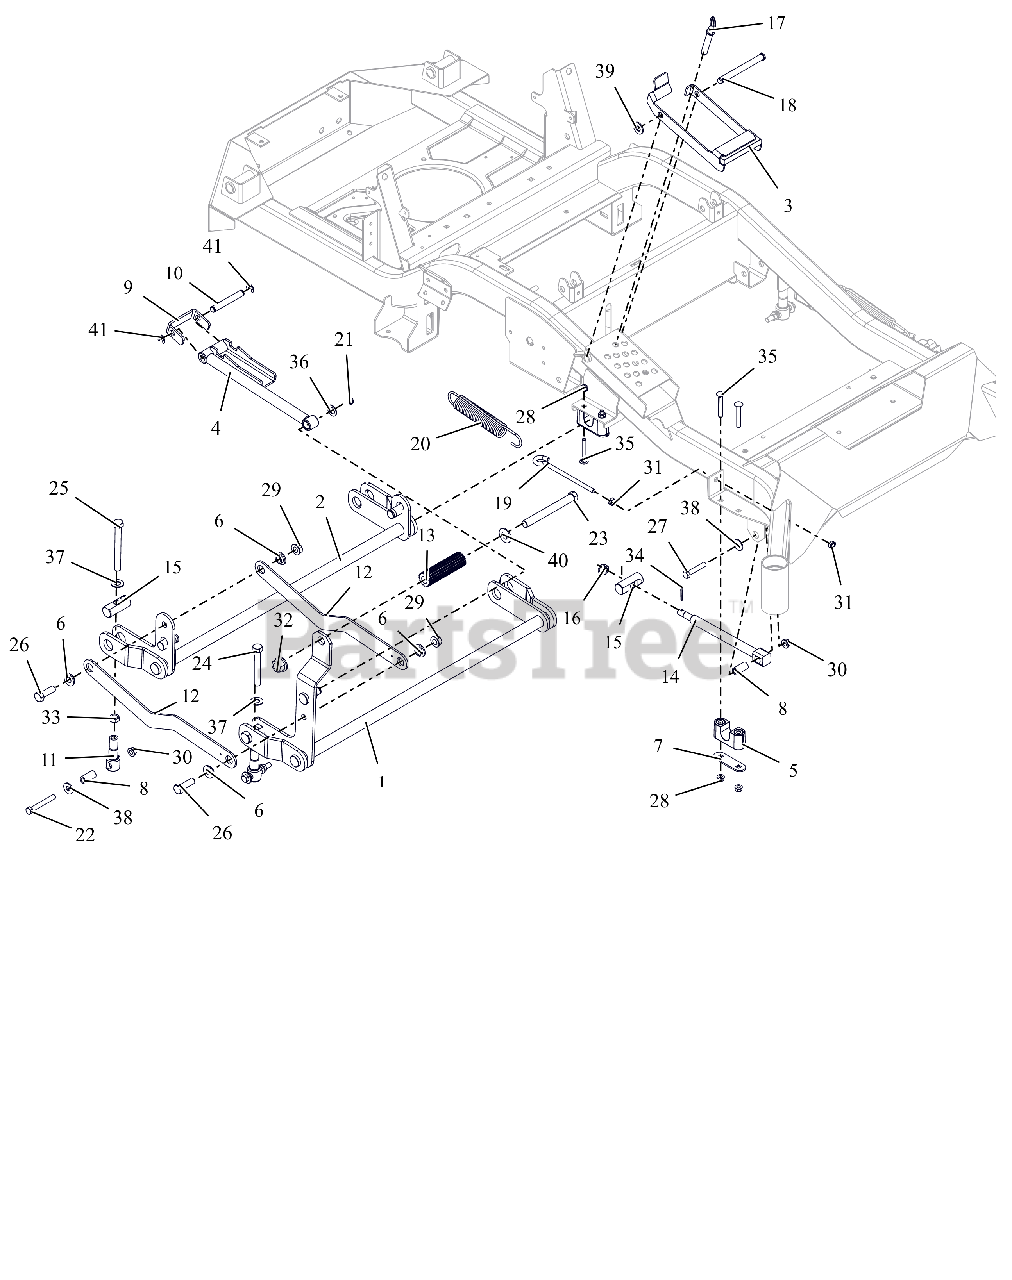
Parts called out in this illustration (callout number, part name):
1	WLDMT, FRONT DECK LIFT PIVOT
2	WLDMT, REAR DECK LIFT PIVOT
3	BRKT, HOC TRANSFER LOCK
4	WLDMT, HOC ARM
5	ASM-BUSHING, DECK LIFT
6	BSHG-FLG .515X.750X.395X1.120
7	PLATE, BEARING SUPPORT
8	SPACER, DECK LEVELING
9	BRKT, HOC LINE
10	ROD, HOC PIVOT
11	LINK, DECK LIFT FORMED
12	LINK, DECK LIFT
13	ROD, FOOT PEDAL (BLACK)
14	DRAG,LINK-HD
15	PIN, DECK LIFT
16	NUT-SL .50-13
17	PIN, .50 X 2.20 USABLE LG BALL
18	PIN-SLIC .50X4.97X4.55 -ZCC
19	BOLT,.38-16 X 5.25-.62 DIA EYE
20	SG-TENS .162X1.25X8.25 WLD 25
21	RG-RTNG-EXT .625X.050
22	BLT, HEX .38-16X2.75 G8 ZCC
23	BLT, HEX .62-11X5.50 G5 FBP
24	BLT, HEX .50-13X3.50F G5 ZCC
25	BLT, HEX .50-13X4.50F G8 ZCC
26	BLT,HEX .50-13X1.50 G5 ZCC
27	BLT,HEX .38-16X2.00 G5 ZCC
28	NUT,LK-CTR-FLG .31-18 GF ZCC
29	NUT-LK-TOP-FLG .500-13 GF ZCC
30	NUT-LK-TOP-FLG .38-16 ZC120
31	NUT-JAM .375-16 G2 ZCC
32	NUT,FLG-TOP LK .625-11 FBP
33	NUT-JAM .500-13 G2 ZCC
34	PIN,CTR.12X1.25EXTPRSQCT ZC120
35	BLT, RHSSN.31-18X2.25 G5 ZCC
36	WSHR, FLT .630X1.005X.062 ZCC
37	WSHR, FLT .557X1.040X.102 ZCC
38	WSHR,FLT .438X1.00X.083 ZCC
39	WSHR,FLT .531X1.062X.095 ZCC
40	WSHRFLT 5/8SAE CARBHARD FBP
41	RG-RTNG-EXT .500X.042 (E)
